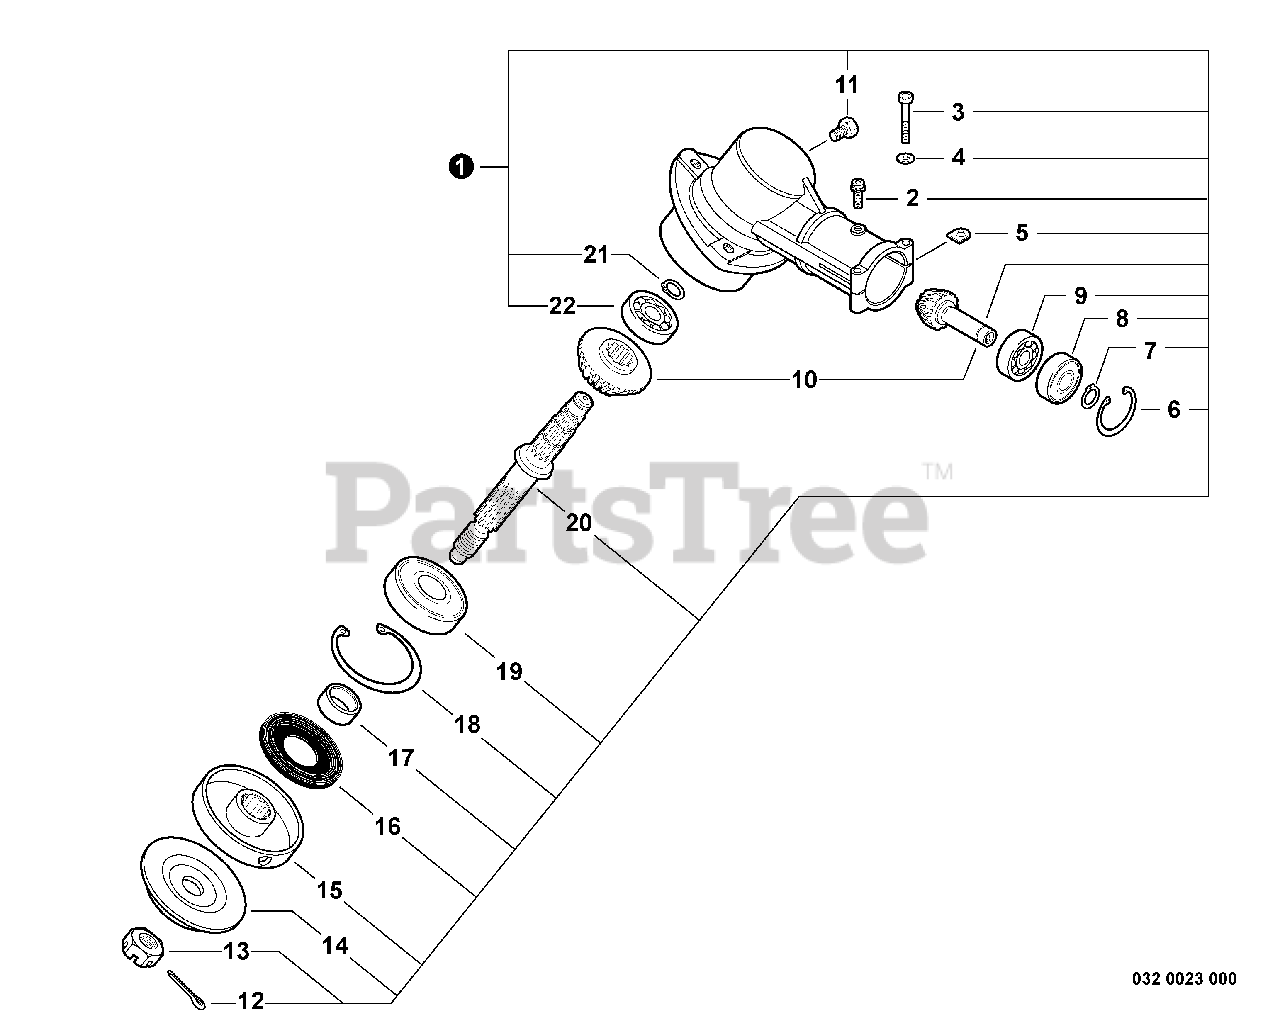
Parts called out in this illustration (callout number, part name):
1	GEAR CASE ASSY
2	SCREW - 5X10
3	BOLT - 5X35
4	WASHER - 5
6	RING, RETAINING - 22
7	RING, RETAINING - 10
8	BEARING, BALL - 6900Z
9	BEARING, BALL - 6900
10	GEAR SET - BEVEL
11	BOLT - 8X8
12	PIN, SPLIT - 2X22
13	NUT - 10 -- LEFT HAND
14	ADAPTOR, BLADE - LOWER
15	ADAPTOR, BLADE - UPPER
16	SEAL, OIL
18	RING, RETAINING - 32
19	BEARING, BALL - 6201
20	GEAR - SHAFT
21	RING, RETAINING - 12
22	BEARING, BALL - 609
